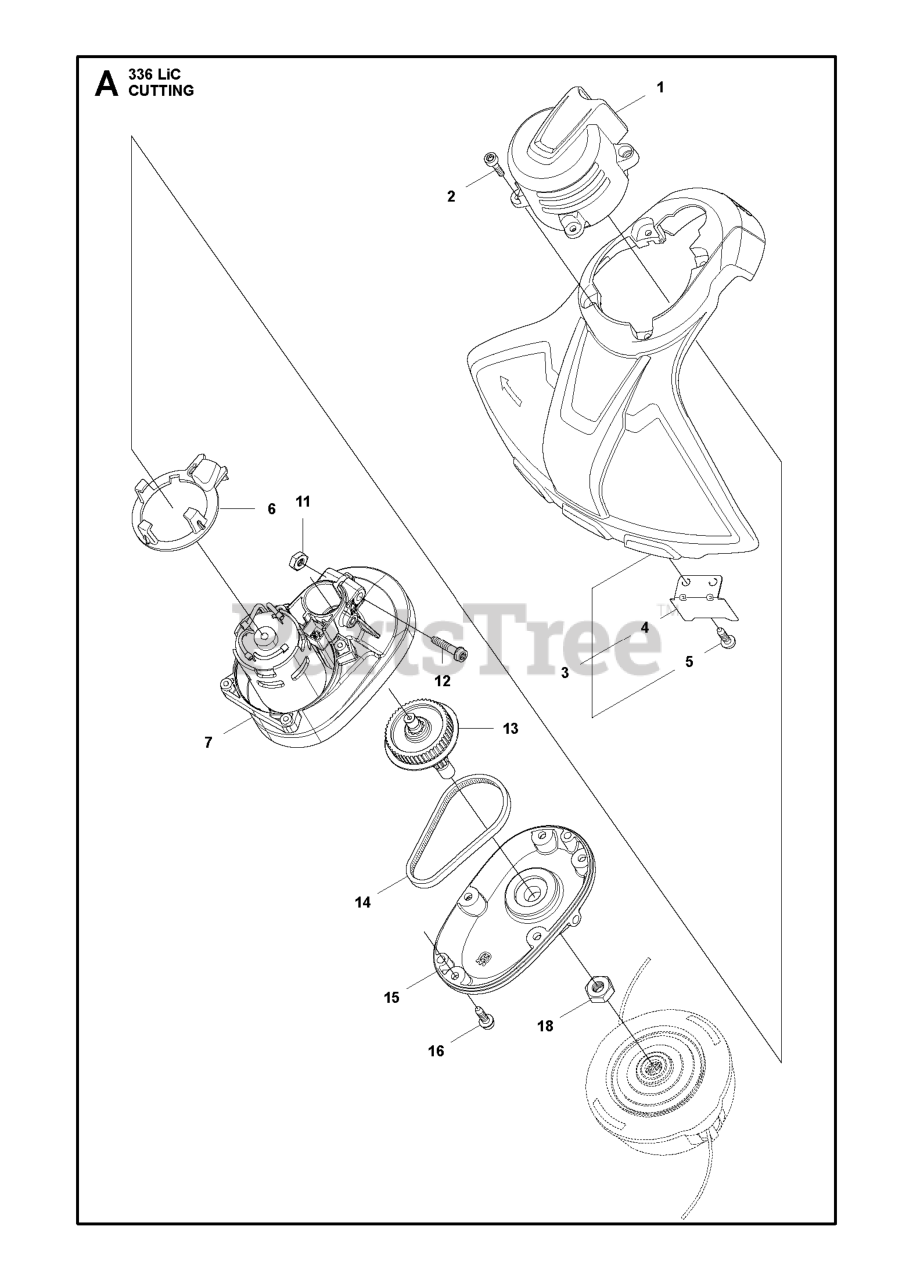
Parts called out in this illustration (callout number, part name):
1	TANK UNIT CPL
1	MOTOR COVER
2	SCREW
3	TRIMMER GUARD
4	THROTTLE ROD
4	LINE LIMITER
6	THROTTLE CATCH
6	INSULATION WALL
7	SPRING PIN 3X24
9	SPRING PIN 3X24
12	SCREW IHSCFM
13	ANTIVIBE ELEMENT
13	BLADE SHAFT
14	ANTIVIBE ELEMENT
16	RP FUEL FILTER
